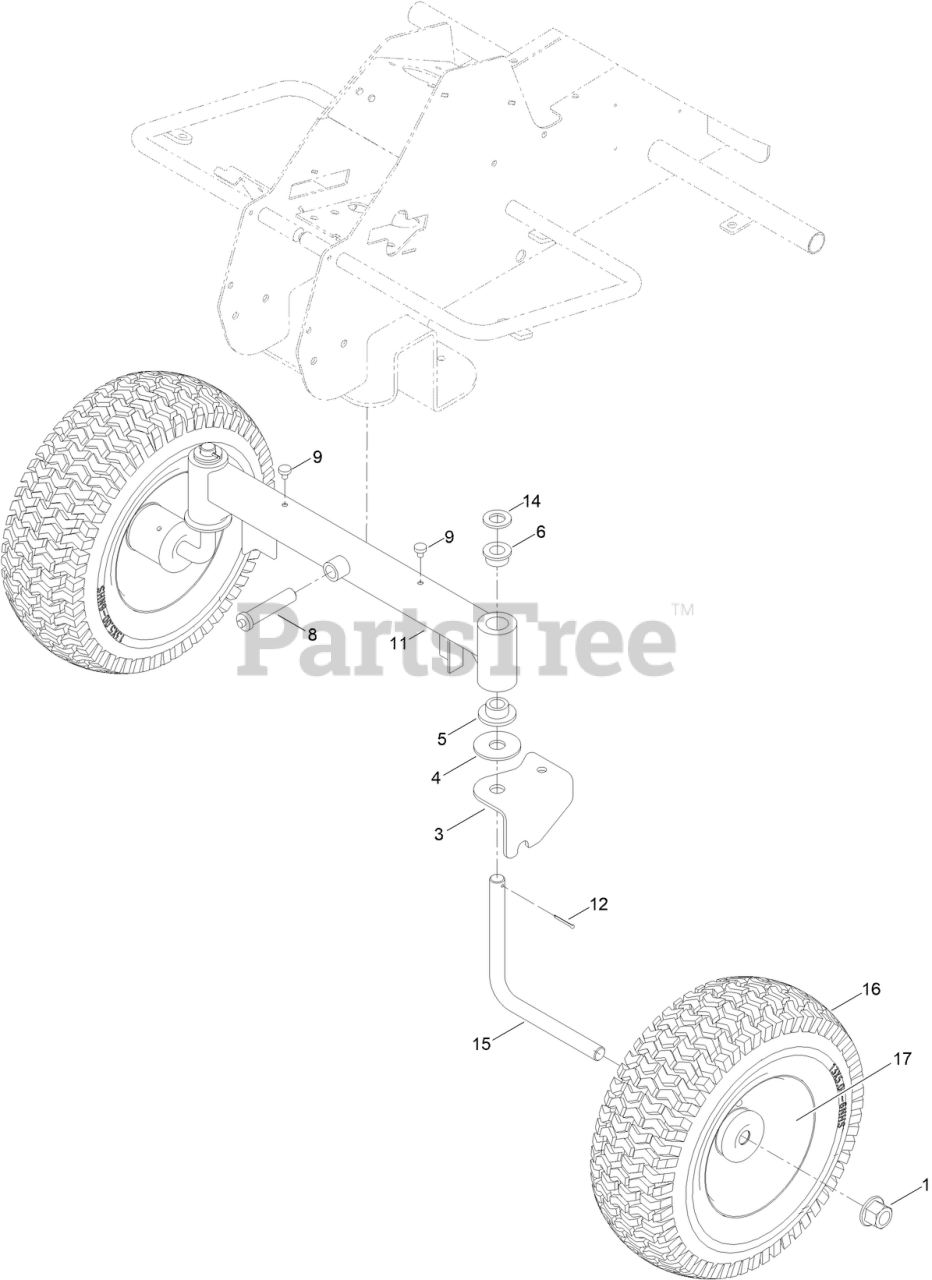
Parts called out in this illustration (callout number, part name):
1	NUT-FLANGE, NI
3	MOUNT FRONT WHEEL
4	WASHER
5	LARGE BUSH, AXLE
6	SMALL BUSH, AXLE
8	PIN, FRONT AXLE TILT
9	STOPPER, FRONT AXLE TILT
11	FRONT AXLE ASM
14	WASHER
15	MOUNT FRONT WHEEL
16	TYRE, WHEEL
17	HUB, WHEEL (FRONT)
